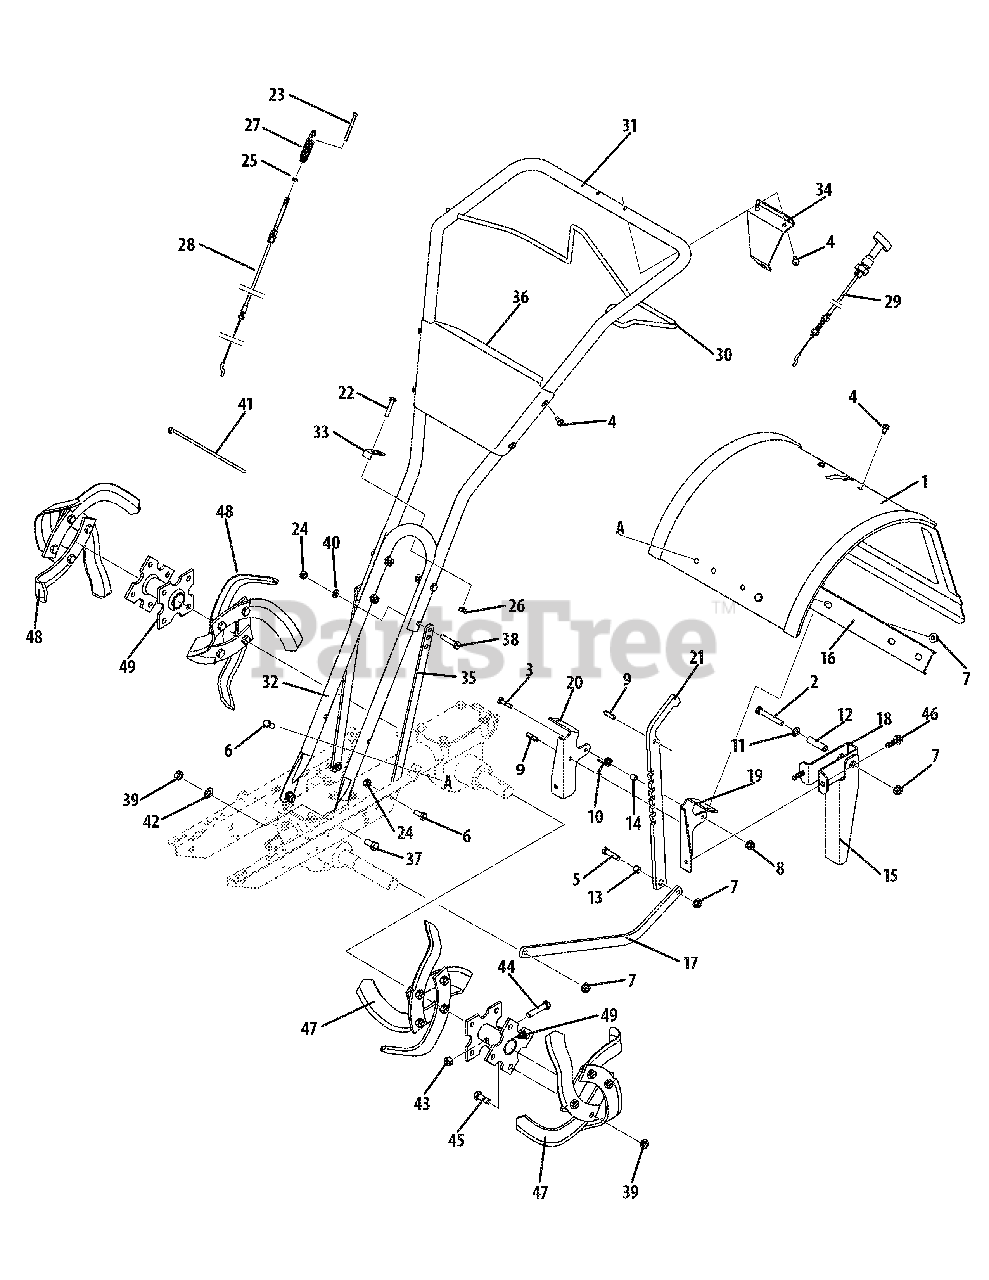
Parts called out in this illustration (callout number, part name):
2	Hex Screw, 5/16-18 x 2.25
3	Hex Head Screw, 1/4-20 x 1
4	Self-Tapping Screw, 1/4-20 x 1/2
5	Hex Head Screw, 5/16-18 x 1-1/4
6	Hex Head Screw, 5/16-18 x .75
7	Nylon Hex Lock Nut, 5/16-18
8	Nylon Hex Lock Nut, 1/4-20
9	Spirol Pin
10	Depth Regulator Spring
11	Flat Washer, 5/16
12	Spacer, .462 x .328 x 1.63
13	Bushing
22	Hex Hd. Screw, 1/4-20 x 1-1/4
23	Screw, #10-24 x 2
24	Hex Lock Nut, 5/16-18
25	Hex Nut, #10-24
26	Hex Lock Nut, 1/4-20
27	Forward Clutch Spring
28	Forward Clutch Cable Assembly
29	Rev. Clutch Cable Assembly
30	Forward Clutch Bail
37	Hex Screw, 3/8-16 x 3/4
38	Hex Screw, 5/16-18 x 1-1/2
39	Hex Lock Nut, 3/8-16
40	Lock Washer, 5/16
41	Cable Tie
42	Flat Washer, 3/8
43	Flange Lock Nut, 3/8 -16
44	Hex Hd. Screw, 3/8-16 x 1-3/4
45	Hex Hd. Screw, 3/8-16 x 1
46	Flange Screw, .312-18 x 1.00
